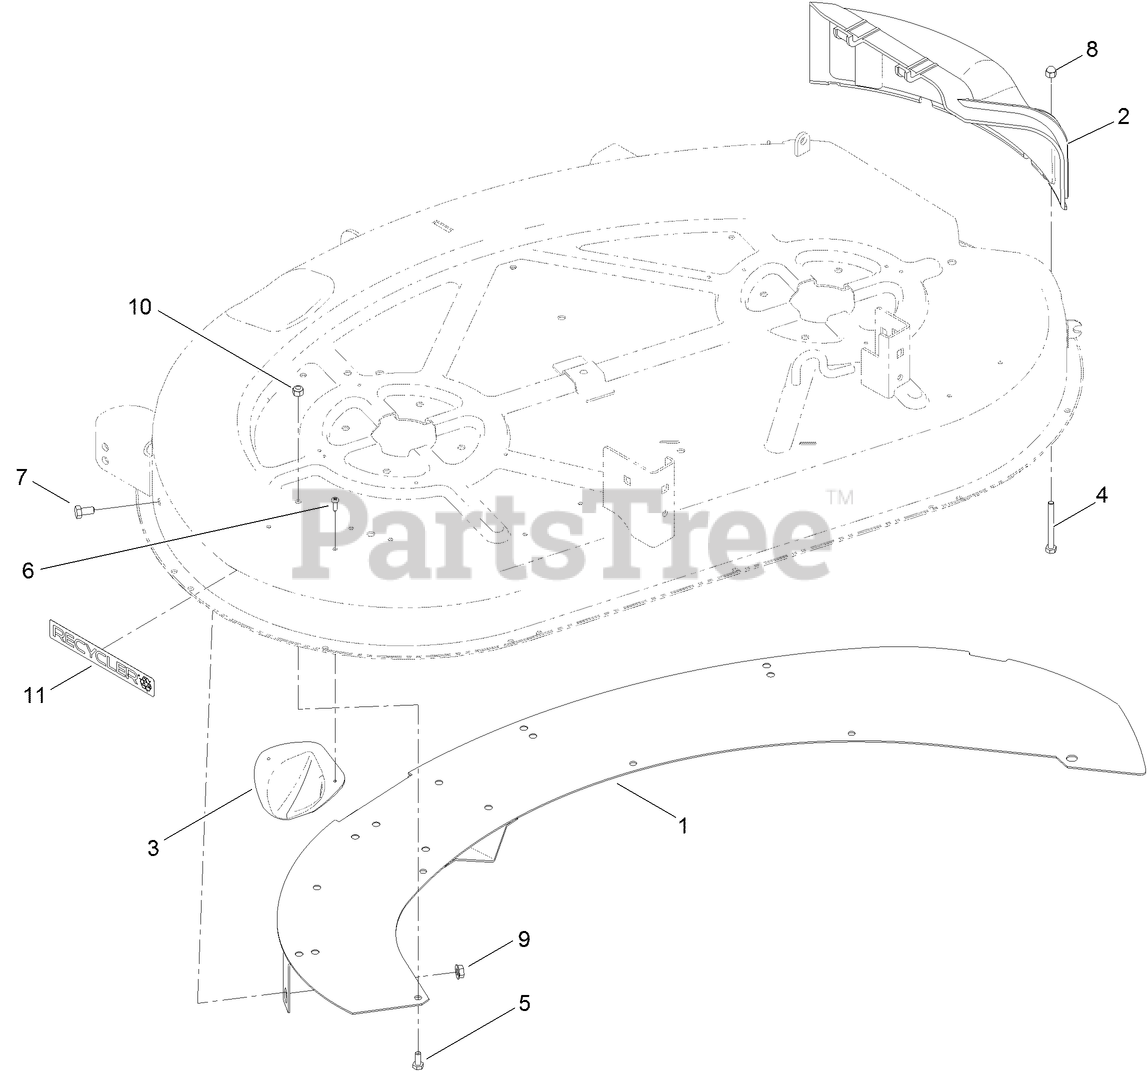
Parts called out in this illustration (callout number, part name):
1	BAFFLE UPPER ASM
2	COVER-DISCHARGE
3	PLATE-KICKER
4	SCREW-HH
5	SCREW-HH
6	SCREW-PPH
7	SCREW-HH
8	NUT-CAP
9	NUT-HF
10	NUT-LOCK, NI
11	DECAL-RECYCLER
